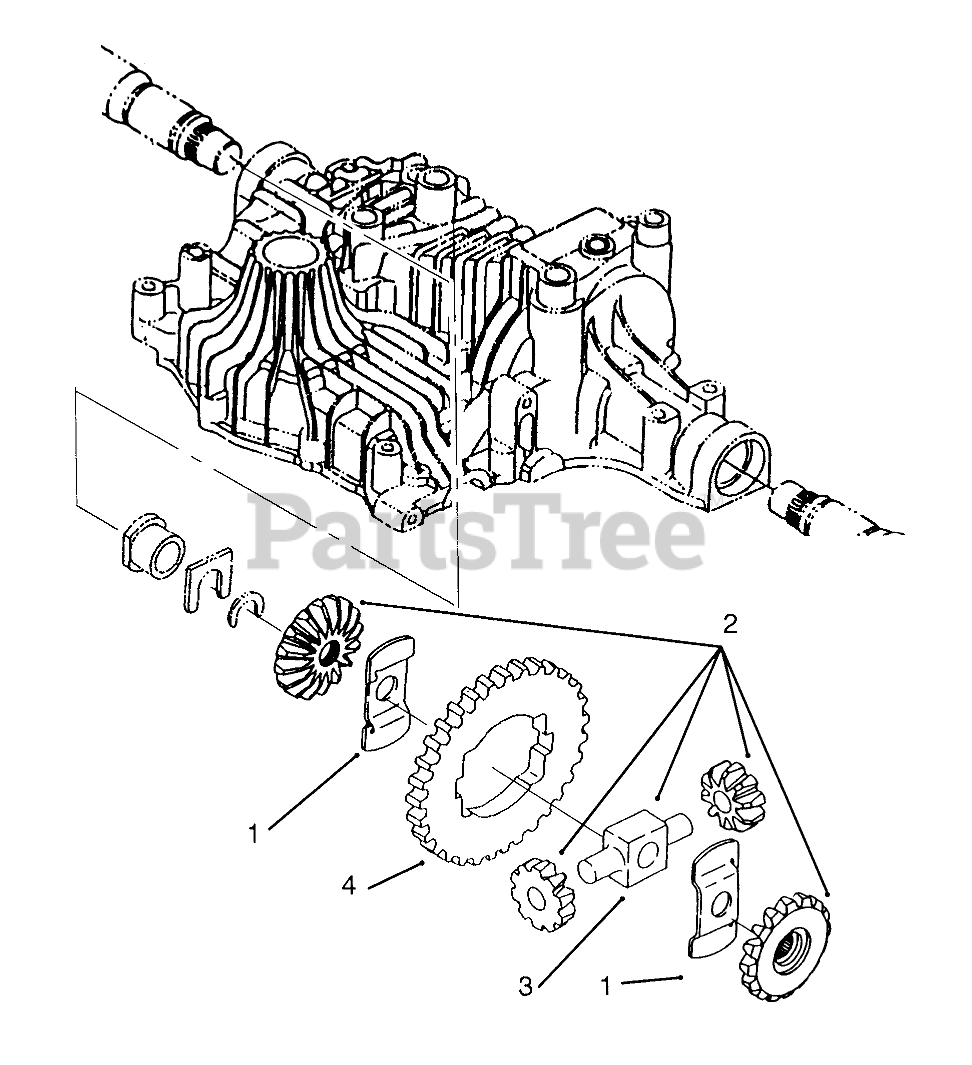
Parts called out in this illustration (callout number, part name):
1	WASHER-THRUST
2	Differential Gear ASM
3	SHAFT - PINION
4	GEAR - FINAL
